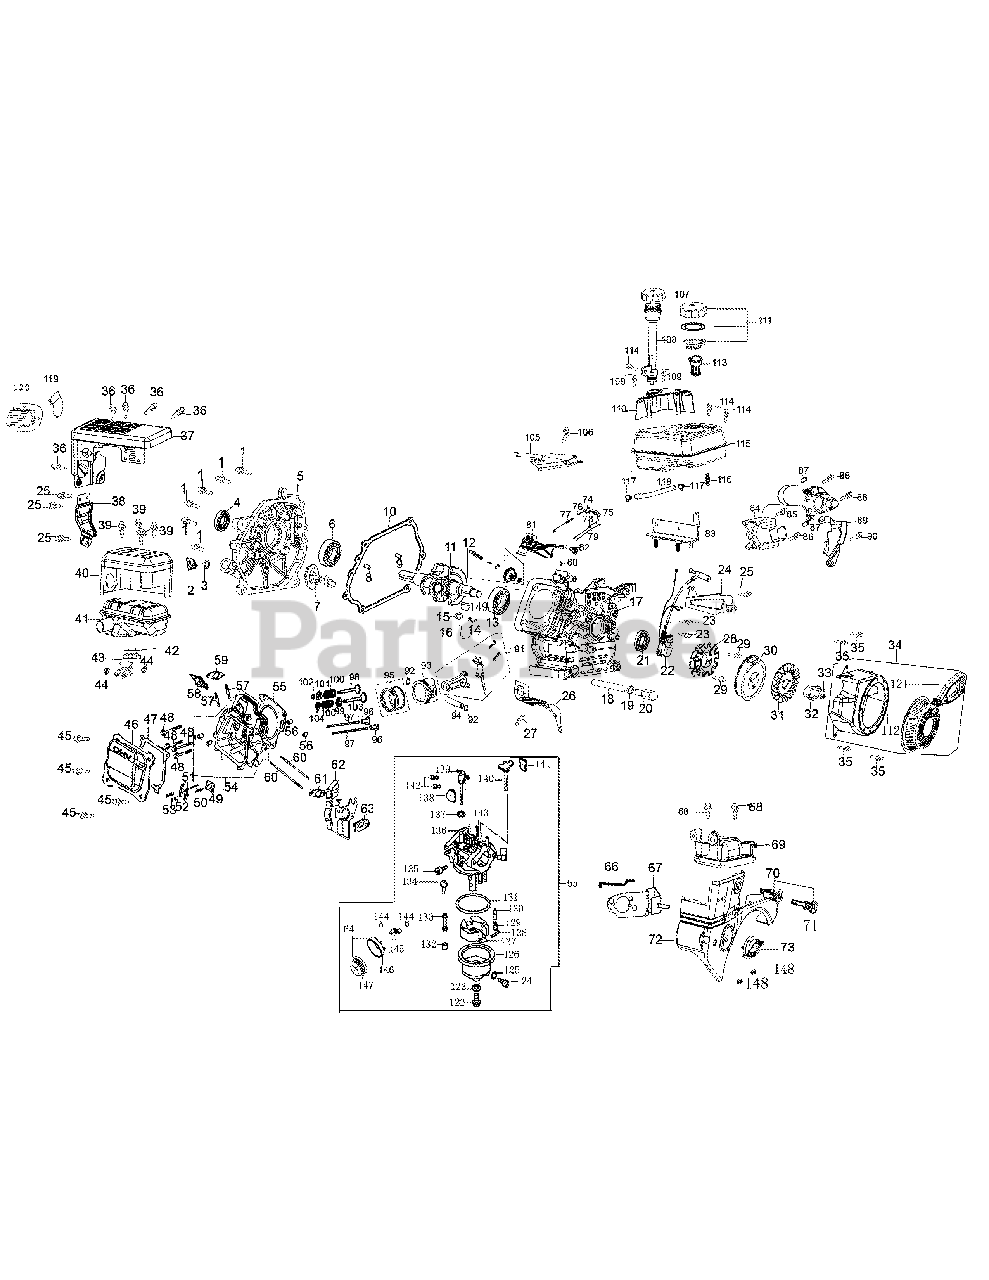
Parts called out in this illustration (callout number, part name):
1	Bolt
2	Oil Filler Plug
2	Drain Bolt
2	Oil Fill Plug
3	O-ring - Oil Filler Plug
3	O-ring
4	Oil Seal
5	Crankcase Cover
6	Radial Ball Bearing
7	Camshaft Assembly
8	Dowel Pin
9	Dowel Pin
10	Crankcase Cover Gasket
10	Case Cover Gasket
11	Crankshaft Assembly
12	Governor Assembly
13	Bearing
14	Pin Lock
15	O-ring
15	O-ring - Governor Arm
16	Governor Arm Shaft
17	Crankcase Complete
18	Oil Drain Pipe
19	Oil Drain Washer
19	Oil Drain Plug Washer
20	Oil Drain Bolt
21	Bearing
22	Ignition Coil
24	Air Flow Shield
26	Air Shield
28	Stator
30	Flywheel
31	Cooling Fan
32	Starter Cup
35	Recoil Mounting Bolts
37	Muffler Shroud
38	Exhaust Pipe Shield
40	Muffler Shield
41	Muffler Assembly
42	Paper Gasket
43	Exhaust Pipe
46	Valve Cover
47	Head Cover Gasket
47	Valve Cover Gasket
48	Bolt- M8 x 55 ZIN
49	Push Rod Guide
50	Rocker Arm Studs
51	Rocker Arm
52	Pivot Adjusting Nut
53	Rocker Arm Lock Nut
55	Cylinder Head Gasket
55	Cylinder Head Gasket 170
56	Dowel Pin
58	Spark Plug
59	Muffler Gasket
60	Muffler Stud Assembly
61	Carb Insulator Gasket
61	Carburetor Insulator Gasket
61	Carburetor Insulator Plate Gasket
61	Carburetor Insulator plate gasket
62	Carburetor Insulator
62	Carburetor Insulator Plate
63	Carburetor Gasket
64	Primer
65	Carburetor Assembly
66	Choke Push Rod
67	Choke Control Bracket
69	Air Filter Heating Pipe Cover
70	Ignition Switch
71	Ignition Key
72	Engine Shroud
73	Choke Lever
77	Governor Spring
78	Throttle Return Spring
79	Governor Rod
81	Throttle Control Assembly
82	Throttle Control Knob
83	Switch Mounting Housing Bracket
84	Electric Starter
89	Blower Housing Shield
91	Connecting Rod Assembly Complete
92	Piston Pin Clip
93	Piston
94	Piston Pin
95	Piston Ring Set - Complete
96	Valve Lifter (Tappet)
97	Push Rod Kit
98	Exhaust Valve
100	Valve Spring
101	Valve Spring Retainers - Exhaust
102	Exhaust Valve Adjuster
103	Intake Valve
104	Valve Spring Retainer- Intake
105	Governor Shield
107	Dipstick
108	Dipstick Tube
110	Cover - Engine/Dipstick
111	Fuel Cap Complete
112	Fan Cover Complete
113	Fuel Filter
115	Fuel Tank
116	Fuel Tank Nipple
117	Fuel Line Clamp
118	Fuel Line
119	Exhaust Deflector Pipe
120	Exhaust Deflector Shield
121	Recoil Starter Assembly
149	Flywheel Key
150	Governor Seal
